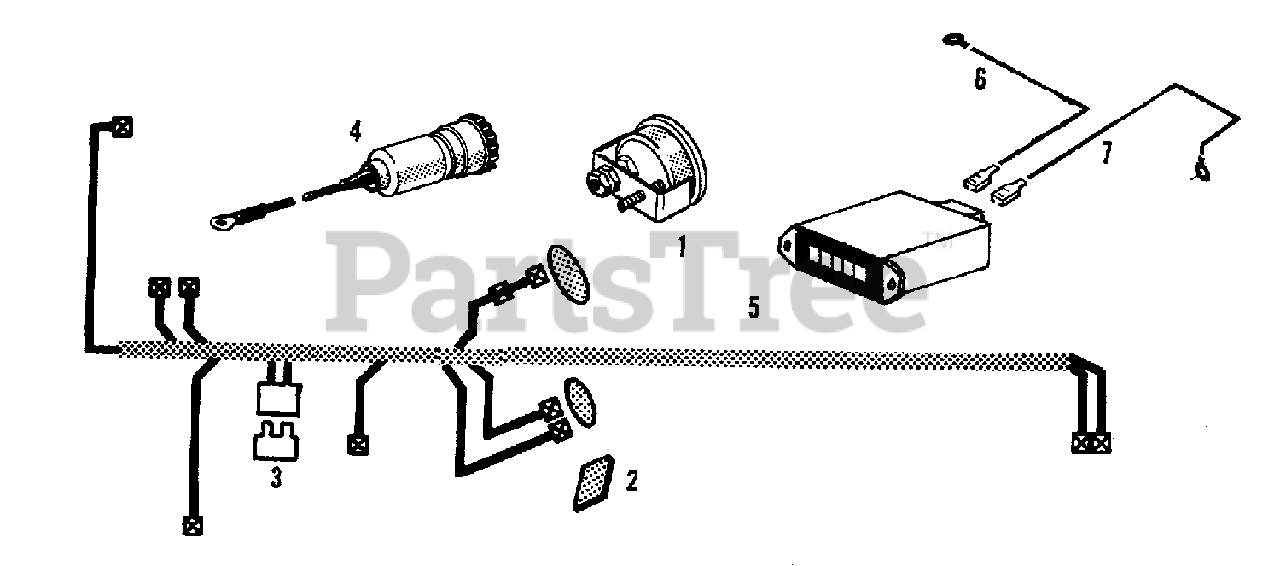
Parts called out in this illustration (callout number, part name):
1	AMMETER, 45-0-45
2	STRIP, Buss Post Insulator
2	WASHER, Insulation
2	NUT, 1/4NC
2	WASHER, 9/32 x 5/8 x 1/16
2	LOCKWASHER, 1/4
3	BREAKER, Circuit
3	BOLT, 1/4NC x 1, Carriage
4	LIGHTER, Cigar
5	HOURMETER
5	CAPSCREW, 1/4NC x 7/8
5	LOCKWASHER, 1/4
5	NUT, 1/4NC
7	LEAD, To Ground
